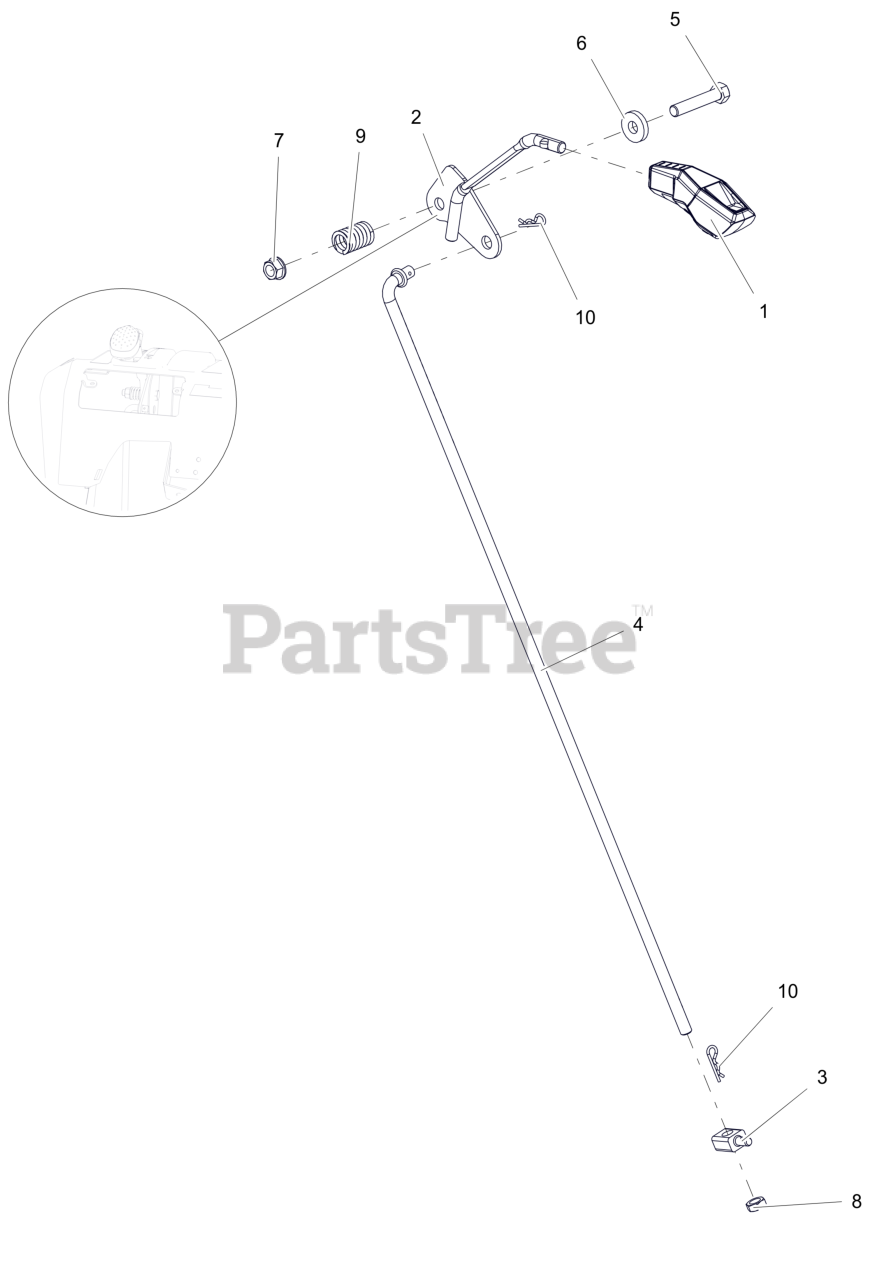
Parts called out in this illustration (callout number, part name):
1	KNOB, CONTROL
2	WELDMENT,LG DASH SPEED CONTROL
3	PIVOT,SHIFT ROD .375-16(TRUNN)
4	ROD, SHIFT - PRO
5	BLT,HEX .38-16X2.00 G5 ZCC
6	WSHR, FLT .406X1.00X.188 ZCC
7	NUT-LK-TOP-FLG .38-16 ZC120
8	NUT-JAM .375-16 G2 ZCC
9	SG-COMP .125X.781X1.250
10	PIN, HAIR #213 .08X1.19 ZCC
